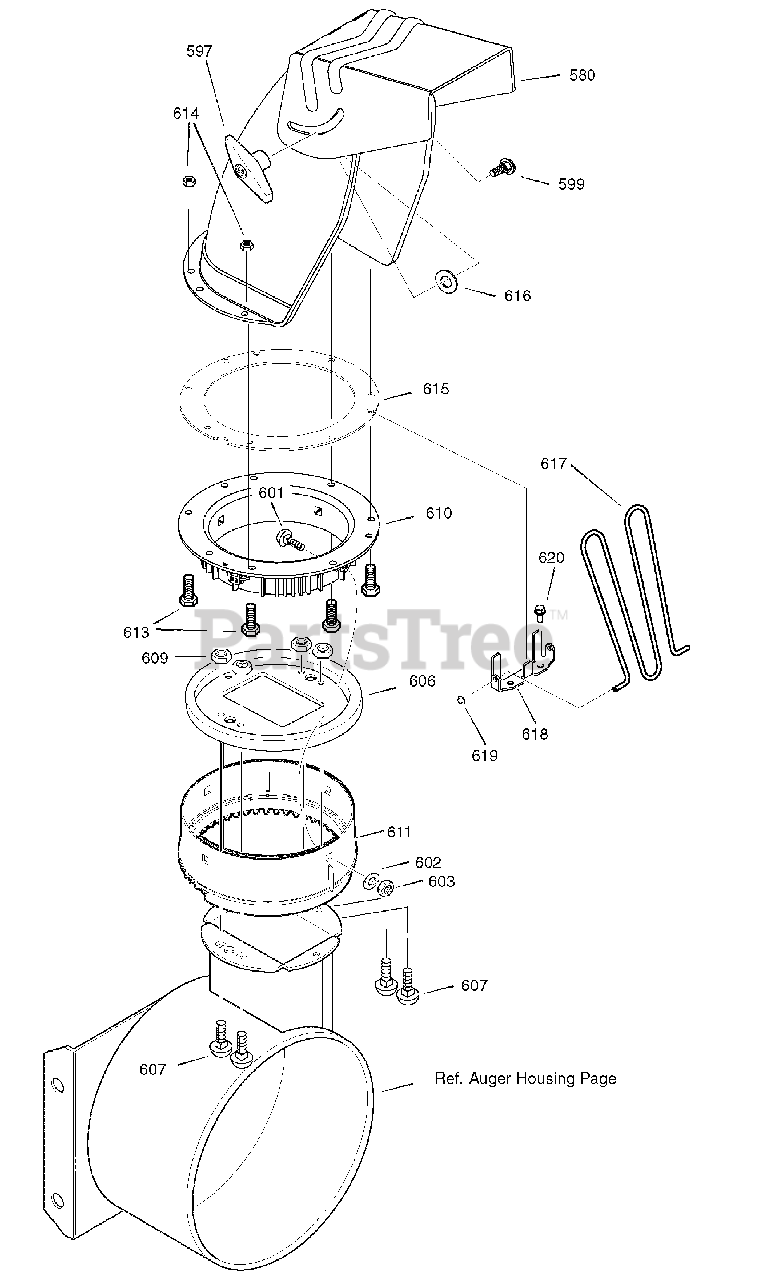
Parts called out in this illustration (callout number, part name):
580	CHUTE ASSEMBLY
597	WING KNOB
599	BOLT, 5/16-18 X .75
601	Bolt, 5/16 X 1.5
602	WASHER, Flat
603	NUT, Hex, Nylock, 5/16-18
606	CHUTE Collar
607	SCREW, 1/4-20 X 0.75
609	NUT, 1/4-20 Hex Nylock
610	RING, Retainer, Inner
611	RING, Retainer, Outer
613	CAPSCREW, Hex-Flange, 1/4-20 x .75
614	NUT, Hex, Nylock Flange, 1/4-20
615	RING, Chute
616	WASHER, Nylon
617	GUARD, Chute
618	BRACKET, Chute Guard
619	NUT, Push
620	SCREW, Hex-Washer, Taptite, 1/4-20 X 1/2"
